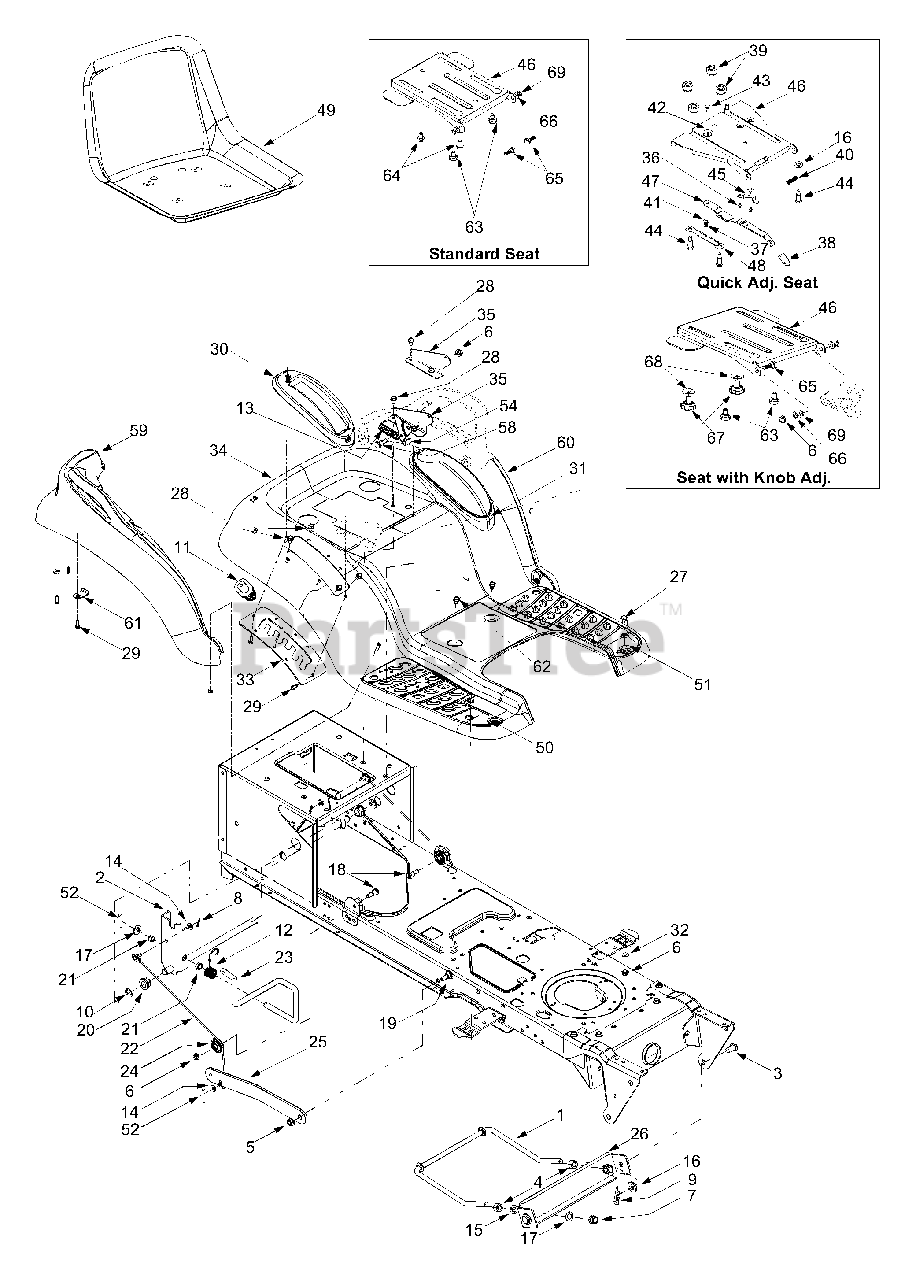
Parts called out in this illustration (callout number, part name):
1	Deck Stabilizer Rod
3	Clevis Pin, .5 x .78
4	Hex Nut, 1/2-13
5	Flange Lock Nut, 3/8-16
6	Lock Nut, 5/16-18
7	Hex Nut, 1/2-13
8	Internal Cotter Pin
9	Internal Cotter Pin
10	E-Ring
11	Handle Grip
12	Torsion Spring
13	Extension Spring, .84 x 4.6
14	Flat Washer, 5/16
15	Lock Washer, 1/2
16	Flat Washer, .31 x 1.062 x .134
17	Flat Washer, .51 x 1.12 x .06
18	Hex Cap Screw, 5/16-18 x .62
19	Shoulder Screw, 3/8-16
20	Hex Flange Bearing
21	Snap Flange Bearing
22	Lift Cable, 16.16
23	Lift Handle
24	Roller Pulley
27	Carriage Bolt, 5/16 x .62
28	AB Screw, 5/16-12 x .75
29	Self-tapping Screw, 1/4-15 x .75
30	Lift Lever Cover
31	Cover w/ Cup Holder
32	Flat Washer, .349 x 1.0 x .063
36	Screw, #10-16 x .375
37	Hex Flange Lock Nut, 1/4-20
38	Seat Adjuster Grip
39	Spacer
40	Compression Spring, .41 x 1.5
41	Spring Washer, .265 x .562 x .025
42	Flat Washer, .344 x .62 x .03
43	Shoulder Screw, .340 x .285,1/4-20
44	Shoulder Screw, .50 x .50, 3/8-16
45	Seat Stop
48	Seat Adjustment Selector
49	High Back Seat, Black
50	RH Foot Pad
51	LH Foot Pad
52	Cotter Pin
54	Seat Lift Bracket
58	Shoulder Screw, .437 x .286
59	RH Fender Flare
60	LH Fender Flare
61	Fender Clips
62	TT Screw 1/4-20 x 0.5
63	Shoulder Screw
64	Hex Washer Hd. Screw
65	Shoulder Screw
66	Flat Washer 5/16
67	Knob 3/8-16
68	Bell Washer
69	Speed Clip
